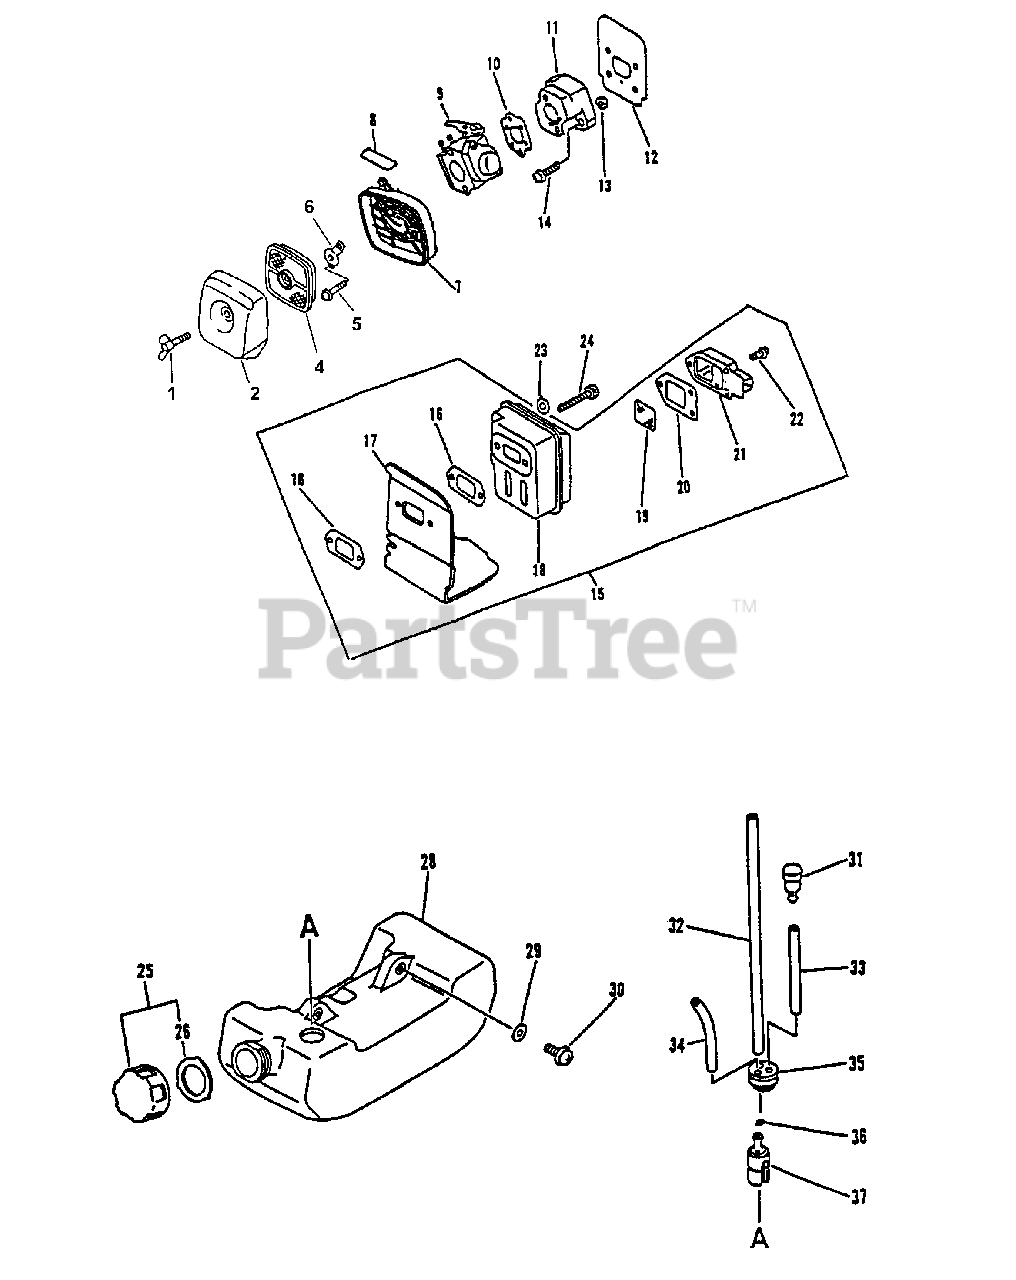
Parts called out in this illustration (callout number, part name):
1	BOLT, WING 5×20
2	COVER, AIR FILTER - GRAY
4	FILTER, AIR - SINGLE LAYER
5	SCREW 5×65
6	PLATE, PREVENT
7	AIR FILTER CASE ASSY
8	LABEL, CHOKE
9	CARBURETOR - C1U-K47
9	CARBURETOR - C1U-K52
10	GASKET, INTAKE
11	INSULATOR, INTAKE
12	HEAT SHIELD, INTAKE
13	NUT M5
14	SCREW 5×20
15	MUFFLER ASSY
16	GASKET, EXHAUST
17	COVER, EXHAUST
19	SCREEN, SPARK ARRESTER
20	GASKET, EXHAUST
21	GUIDE, EXHAUST - INNER
22	SCREW 4×10
23	WASHER, FLAT 5.5×10×0.8
24	BOLT 5×55
25	CAP ASSY
26	GASKET, FUEL CAP
28	TANK, FUEL
29	WASHER 5.5×12×0.8
30	SCREW 5×16
31	VENT ASSY
32	PIPE, FUEL 3x-5x-180
33	PIPE, FUEL 3x-5x-70 BLACK
34	PIPE, FUEL 3×6×80 CLEAR
35	GROMMET, FUEL
36	CLIP 6 MM
37	FILTER, FUEL
